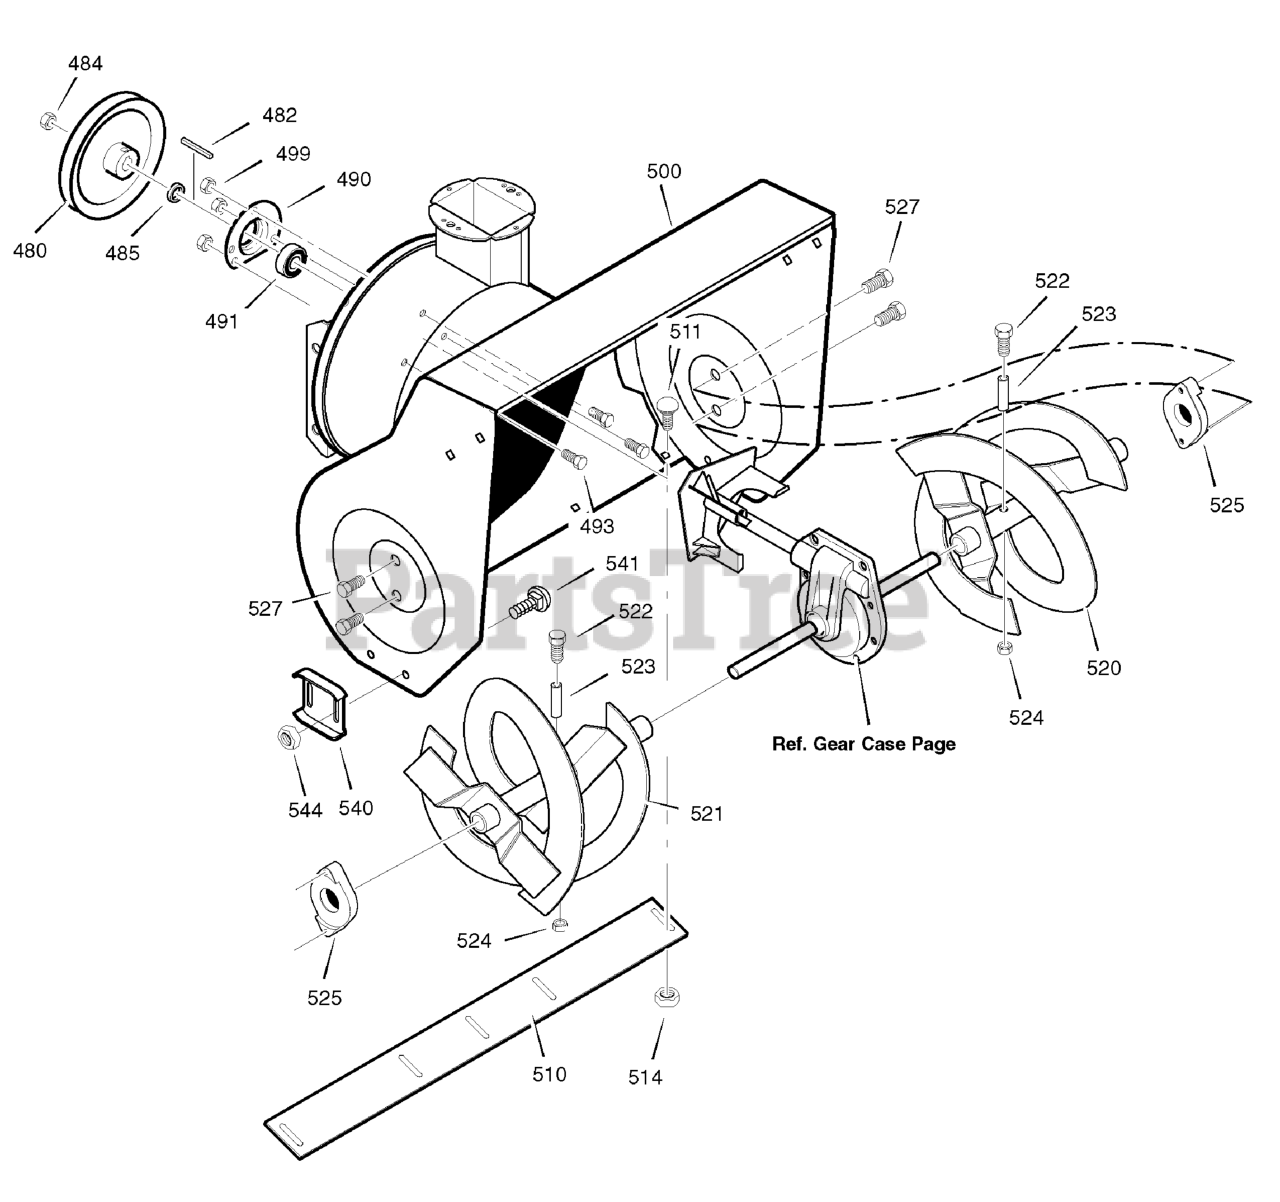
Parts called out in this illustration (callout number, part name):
480	PULLEY, 4L 8.40 OD
482	KEY, SQUARE 3/16 X 3/4
484	NUT, 1/2-20
485	SPACER, FRICTION PULLEY
490	RETAINER, BALL BRNG
491	BEARING, BALL
493	BOLT, HEX 5/16-18X .50
499	NUT, 5/16-18 HEXWDFLLK
500	HOUSING, ASSY
510	BLADE, SCRAPER
511	BOLT, 5/16-18X.75
514	NUT, 5/16-18
520	AUGER, ASSY, LH
521	AUGER, ASSY, RH
522	SCREW, 1/4-20 X 1.75
523	SPACER, SLEEVE
524	NUT, 1/4-20
525	BEARING, FLANGE
527	SCREW, 5/16-18 x 0.75
540	SKID, HEIGHT ADJUST
541	BOLT, 5/16-18 X .75
544	NUT, 5/16-18
